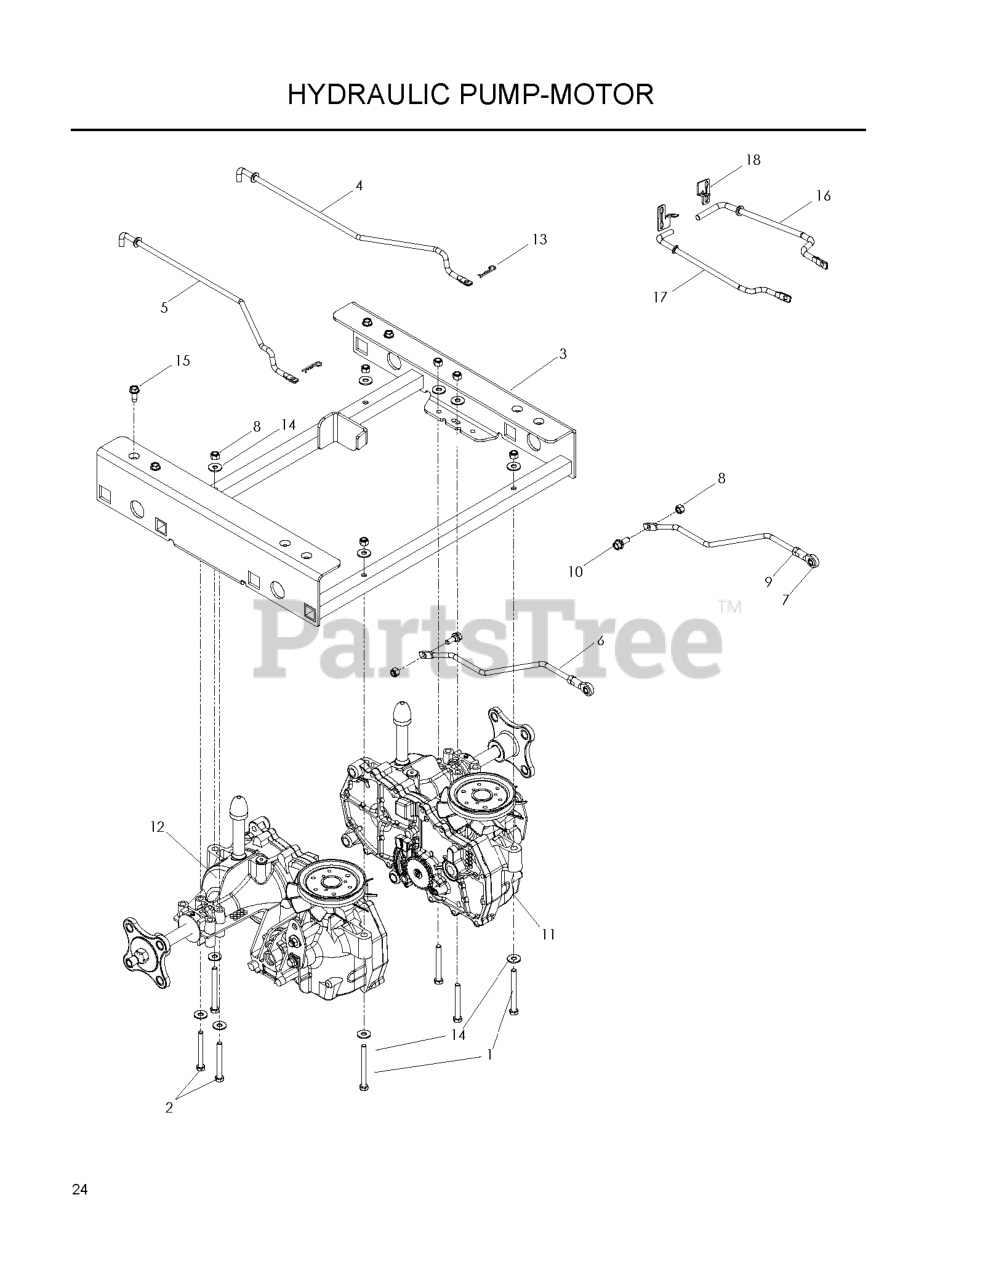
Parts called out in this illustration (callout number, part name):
1	HCS 5/16-18 X 3 1/4
2	HCS 5/16C X 2-3/4
3	SUB FRAME PAINTED
4	BYPASS LINKAGE, LEFT
5	BYPASS LINKAGE, RIGHT
6	MOTION CONTROL ROD ASM
7	BALL JOINT, RIGHT HANDED
8	NUT 5/16 NYLOC
10	BOLT, SHOULDER
11	HG_EZT, LT
12	HG_EZT RIGHT
13	HAIRPIN #2
14	WASHER 5/16 FLAT
16	LINKAGE, LEFT BYPASS
17	LINKAGE, RIGHT BYPASS
18	BRACKET, BYPASS - BLACK
